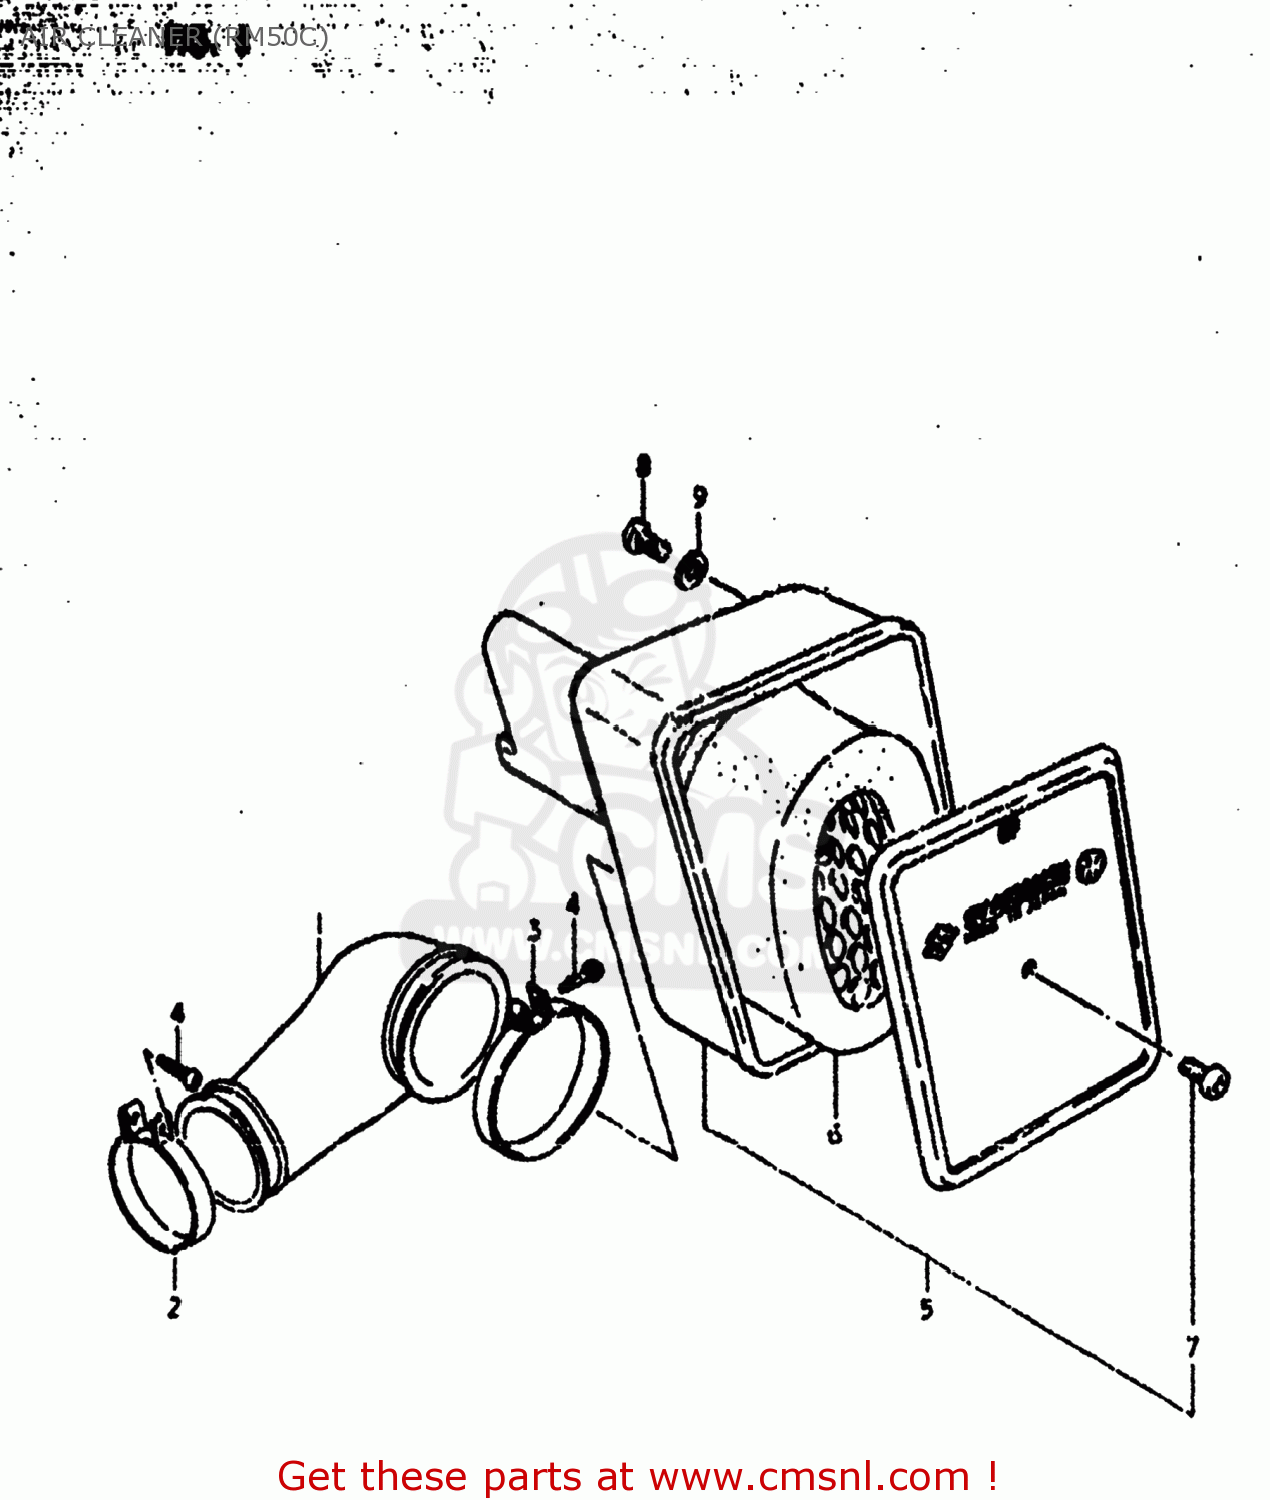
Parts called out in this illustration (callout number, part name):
1	HOSE,CARBURETOR AIR INLET
2	CLAMP
3	CLAMP
4	SCREW
5	CLEANER ASSY,AIR
6	FILTER
7	SCREW
8	SCREW
9	WASHER
